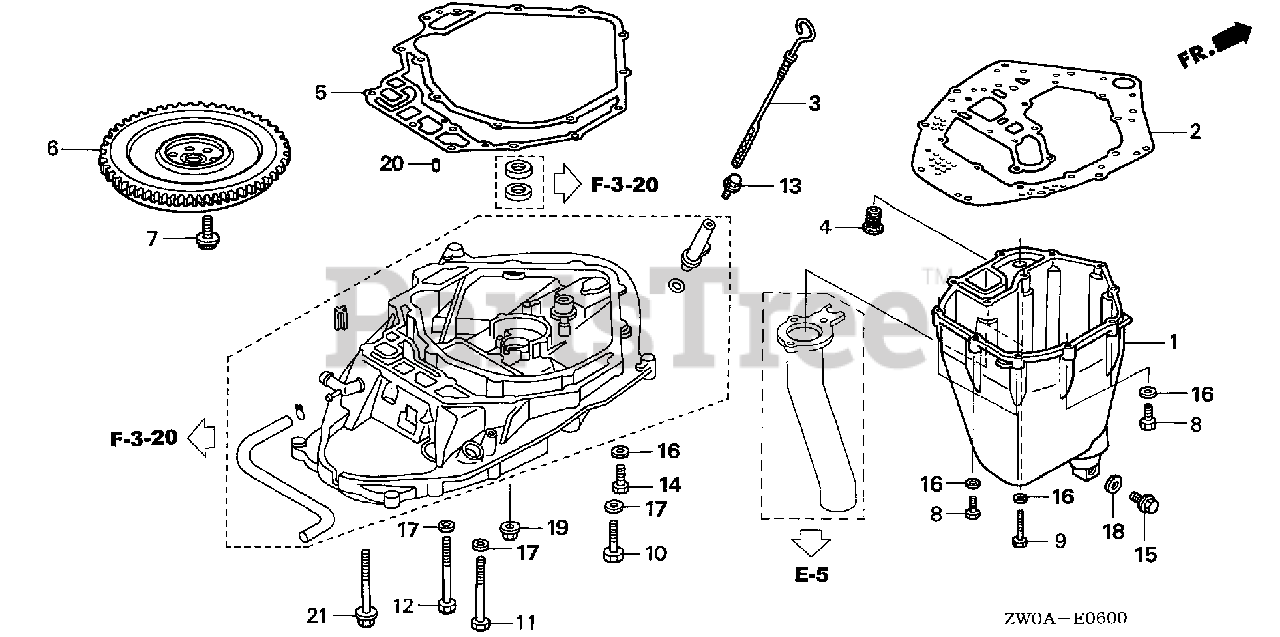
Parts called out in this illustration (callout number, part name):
1	PAN, OIL *TGRAY* (GRAY)
2	GASKET, OIL PAN
3	DIPSTICK, OIL
4	GROMMET, WATER TUBE
5	GASKET, MOUNT CASE
6	FLYWHEEL *TBLACK* (BLACK)
7	BOLT (12MM)
8	BOLT, HEX. (8X35)
9	BOLT, HEX. (8X55)
10	BOLT, HEX. (10X47)
11	BOLT, HEX. (10X110)
12	BOLT, HEX. (10X90)
13	BOLT, FLANGE (6X12)
14	BOLT, HEX. (8X25)
15	BOLT, DRAIN PLUG
16	WASHER, PLAIN (8MM)
17	WASHER, PLAIN (10MM)
18	WASHER, DRAIN PLUG (12MM)
19	NUT, FLANGE (10MM)
20	PIN, DOWEL (6X10)
21	BOLT, FLANGE (10X110)
